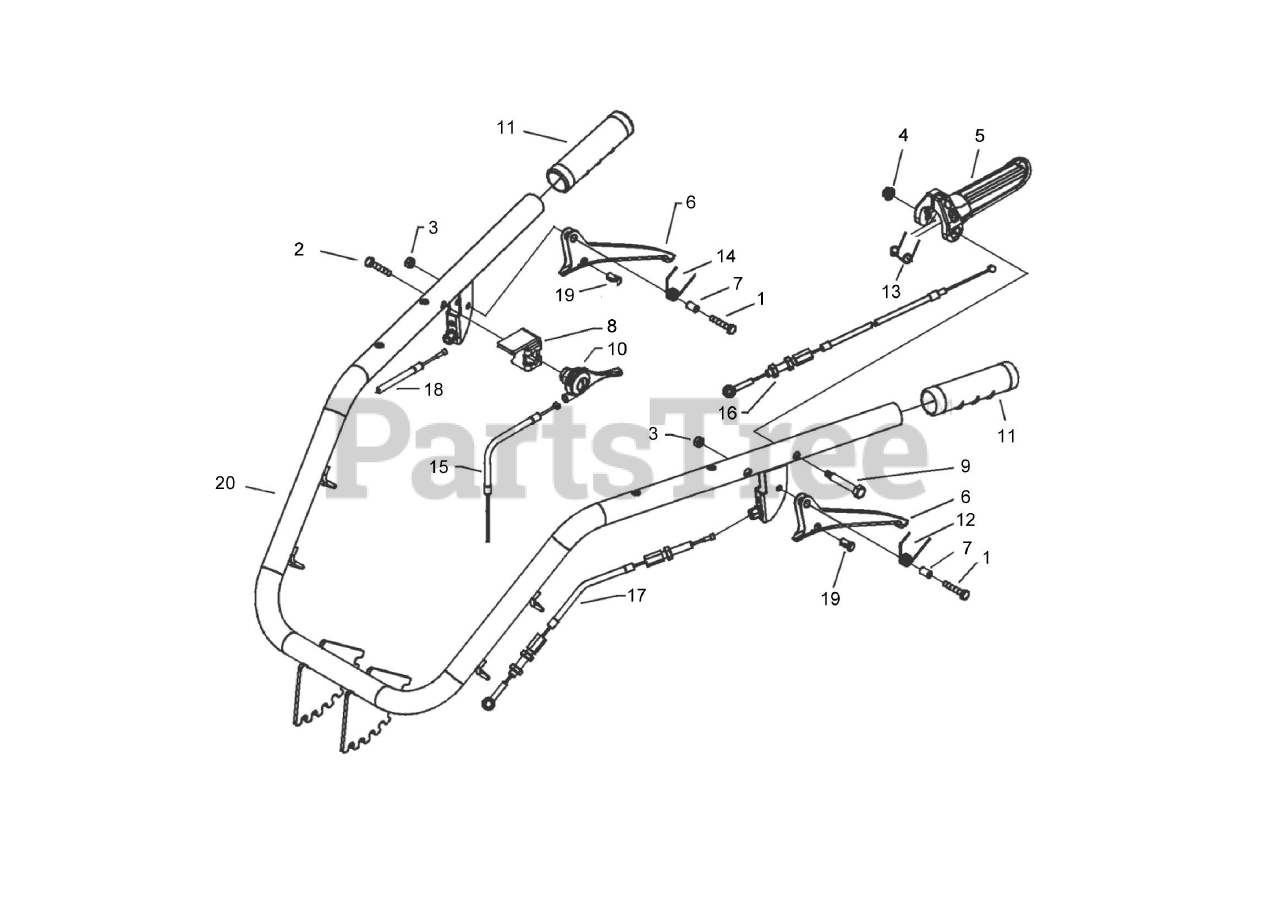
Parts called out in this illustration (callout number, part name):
1	SCREW M6X25
2	SCREW
3	LOCKNUT M6
4	LOCKNUT M6
5	LEVER
6	LEVER
7	SPACER
8	PANEL
9	LEVER PIN
10	THROTTLE LEVER
12	SPRING
13	SPRING
14	SPRING
15	CABLE & SHEATH, THROTTLE
16	CABLE & SHEATH, OPC
17	CABLE & SHEATH, CLUTCH
18	CABLE & SHEATH, HANDLEBAR RELEASE
19	CABLE CLAMP
20	HANDLE BAR
